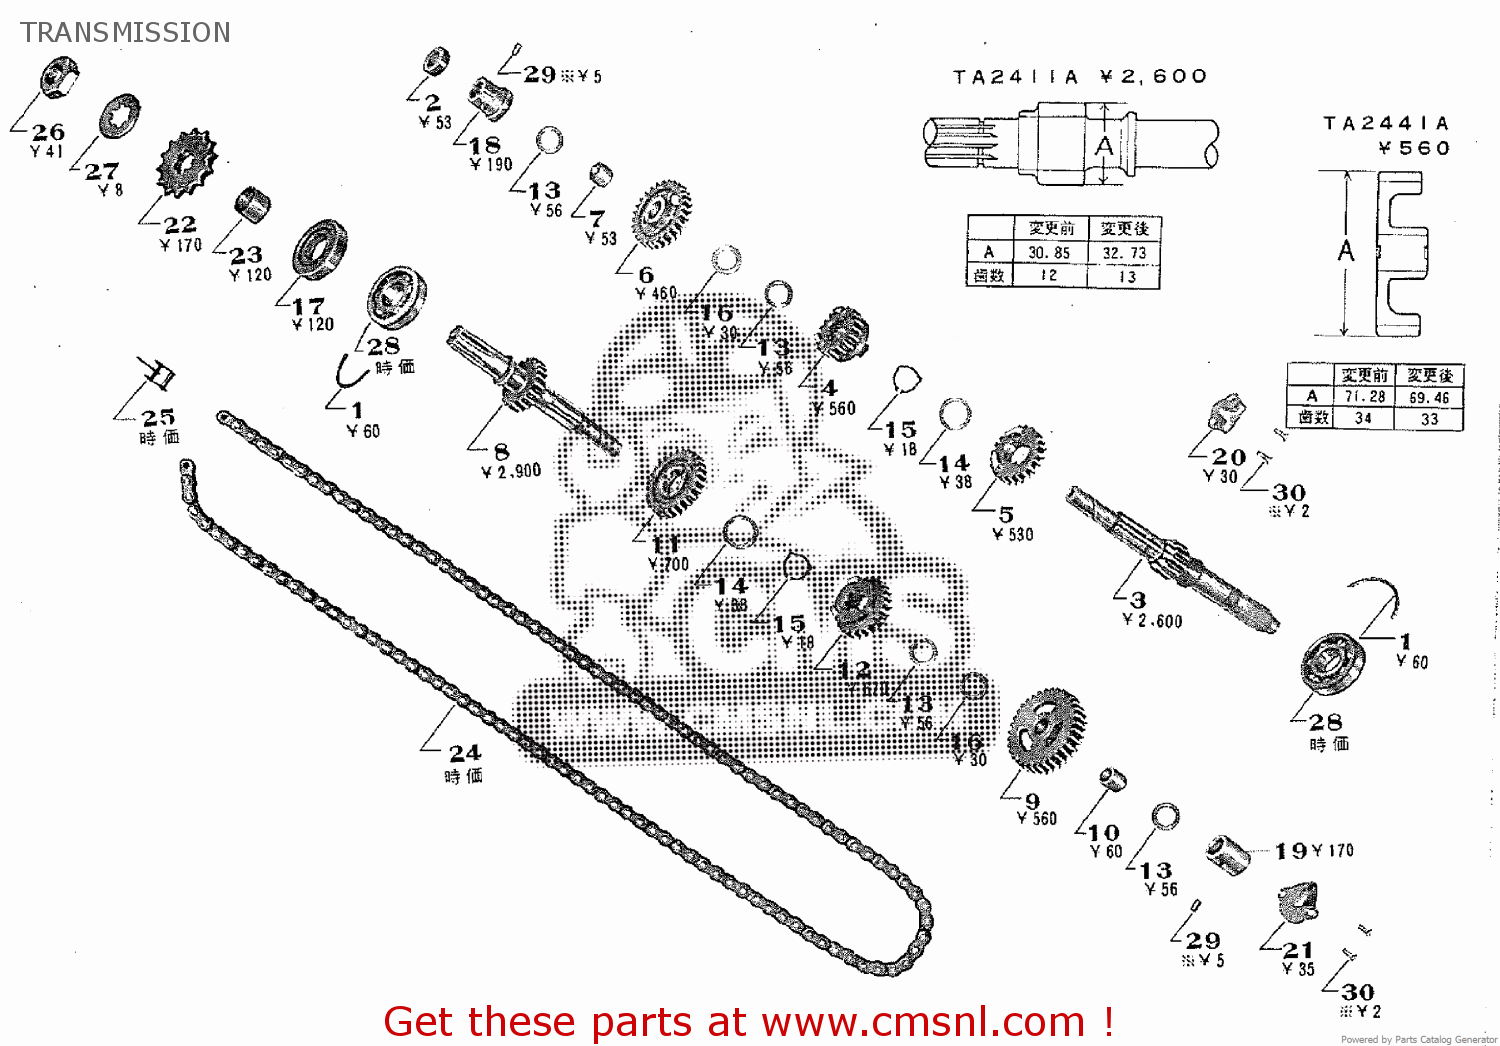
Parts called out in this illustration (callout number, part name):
1	BEARING KNOCK RING
2	PUSH ROD OIL SEAL
3	COUNTER SHAFT
4	SECOND PINION
5	THIRD PINION
6	TOP PINION COMP.
7	TOP PINION BUSH
8	DRIVE SHAFT
9	LOW GEAR COMP.
10	LOW GEAR BUSH
11	SECOND GEAR
12	THIRD GEAR
13	TOP PINION THRUST WASHER
14	THRUST WASHER
15	SET CIRCLIP
16	THRUST ADJUSTER WASHER
17	DRIVE SHAFT OIL SEAL
18	COUNTER SHAFT OIL SEAL
19	DRIVE SHAFT BUSH
20	COUNTER SHAFT OIL CUP
21	DRIVE SHAFT OIL CUP
22	DRIVE SPROCKET
23	DRIVE SPROCKET DISTANCE COLLAR
24	DRIVE CHAIN ASSY.
25	DRIVE CHAIN JOINT COMP.
26	PRIMARY PINION SET NUT
27	DRIVE SPROCKET SET WASHER
28	SLOTTED BEARING
29	6X10 ROLLER
30	5X10 SCREW
